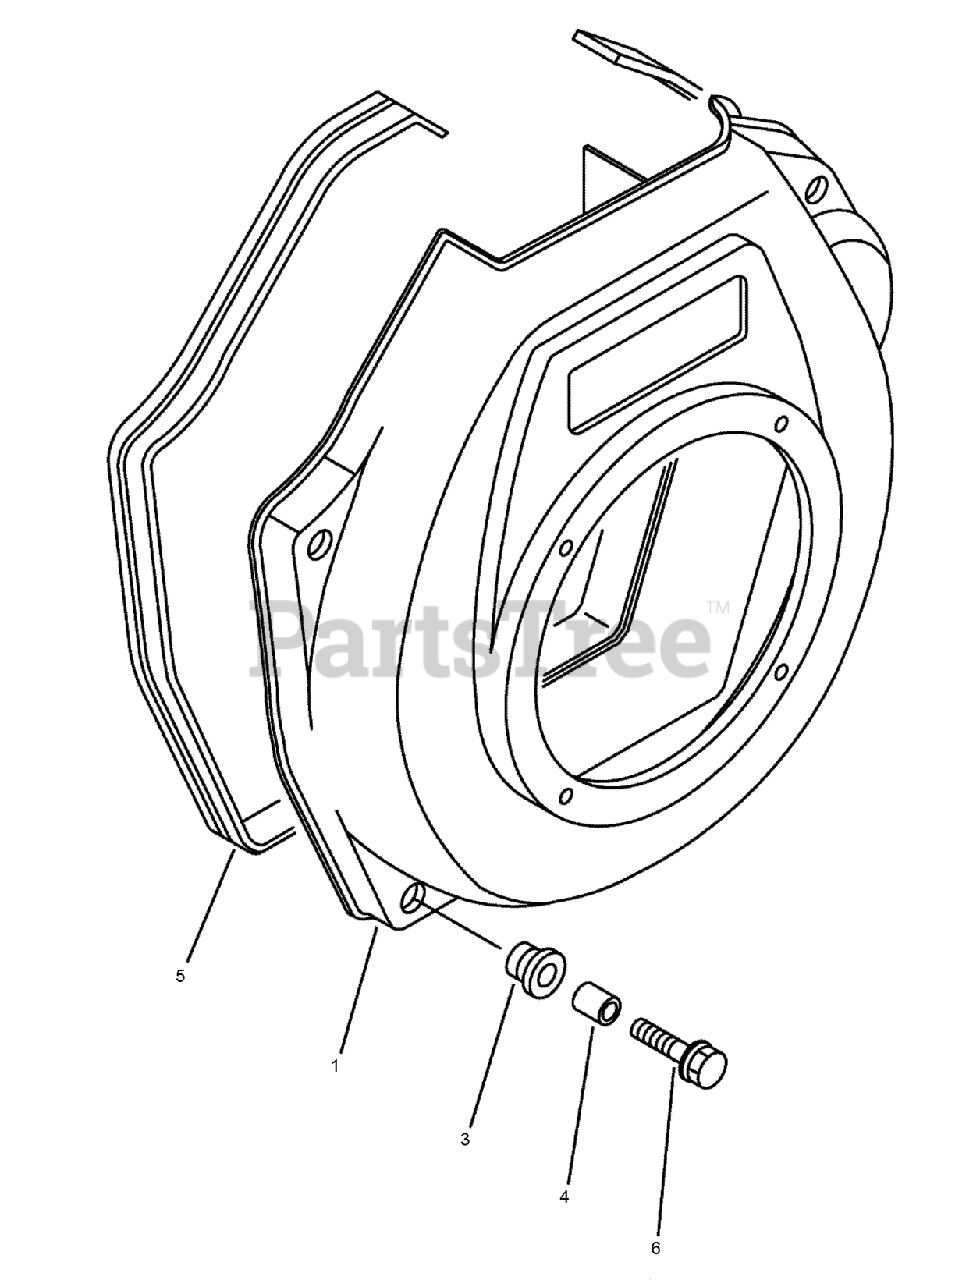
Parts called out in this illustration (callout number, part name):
1	CASE-FAN, COOLING
3	CUSHION-RUBBER
4	COLLAR
5	SEAL-CASE, FAN
